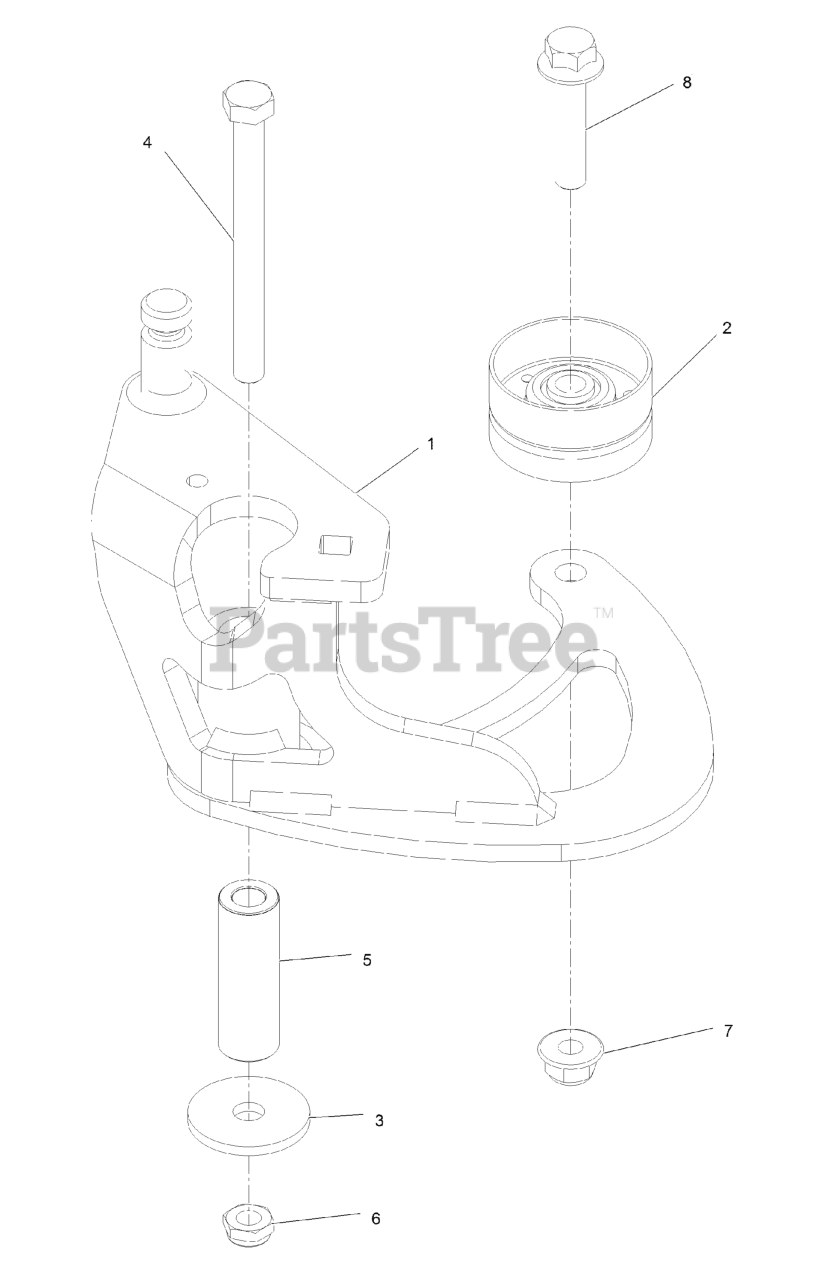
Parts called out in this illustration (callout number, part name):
1	ASM, IDLER ARM W/ BUSHINGS
2	IDLER, FLAT
4	SCREW-HH
5	TUBE, IDLER PIVOT
7	NUT-HF, NI
8	SCREW-HHF
